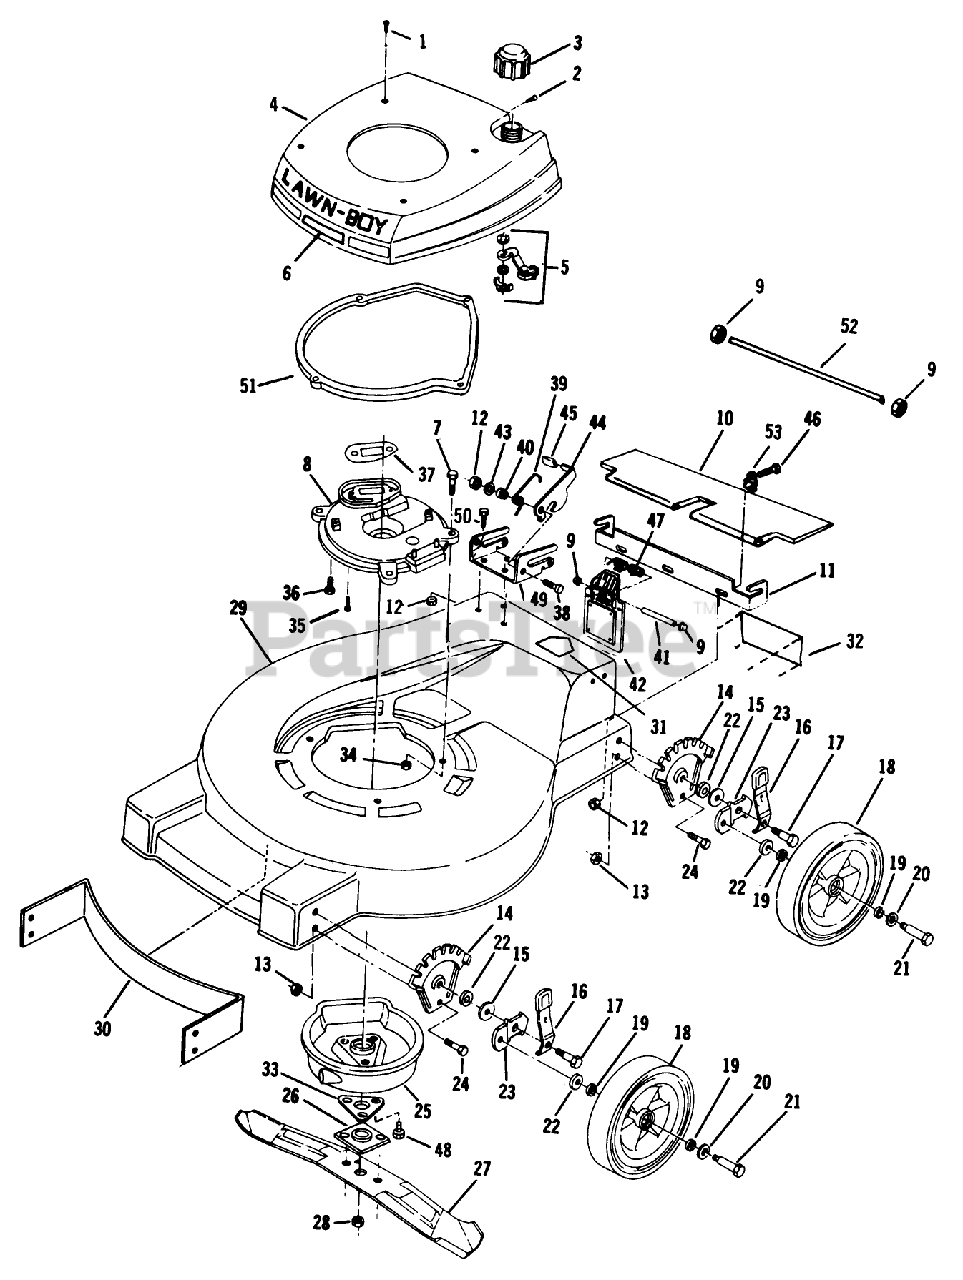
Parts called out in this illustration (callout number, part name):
1	SCREW LAWRENCE
2	SCREW S
3	FUEL CAP & INSERT
7	SCREW-HH
8	PLATE,MUFFLER F
10	T/SHIELD SM&P
12	LOCKNUT E
13	LOCKNUT
15	WASHER
16	KNOB & SPRING
17	BOLT
19	WASHER
20	SPACER
21	BOLT WHEEL
22	WASHER WROUGHT
26	PLATE AND COLLAR ASM
28	NUT-BLADE
33	SUPPORT F
34	NUT-LOCK F
35	SCREW V
39	SPRING
41	ROD ROCK/HDWE
47	SPRING ASOC
48	SCREW
